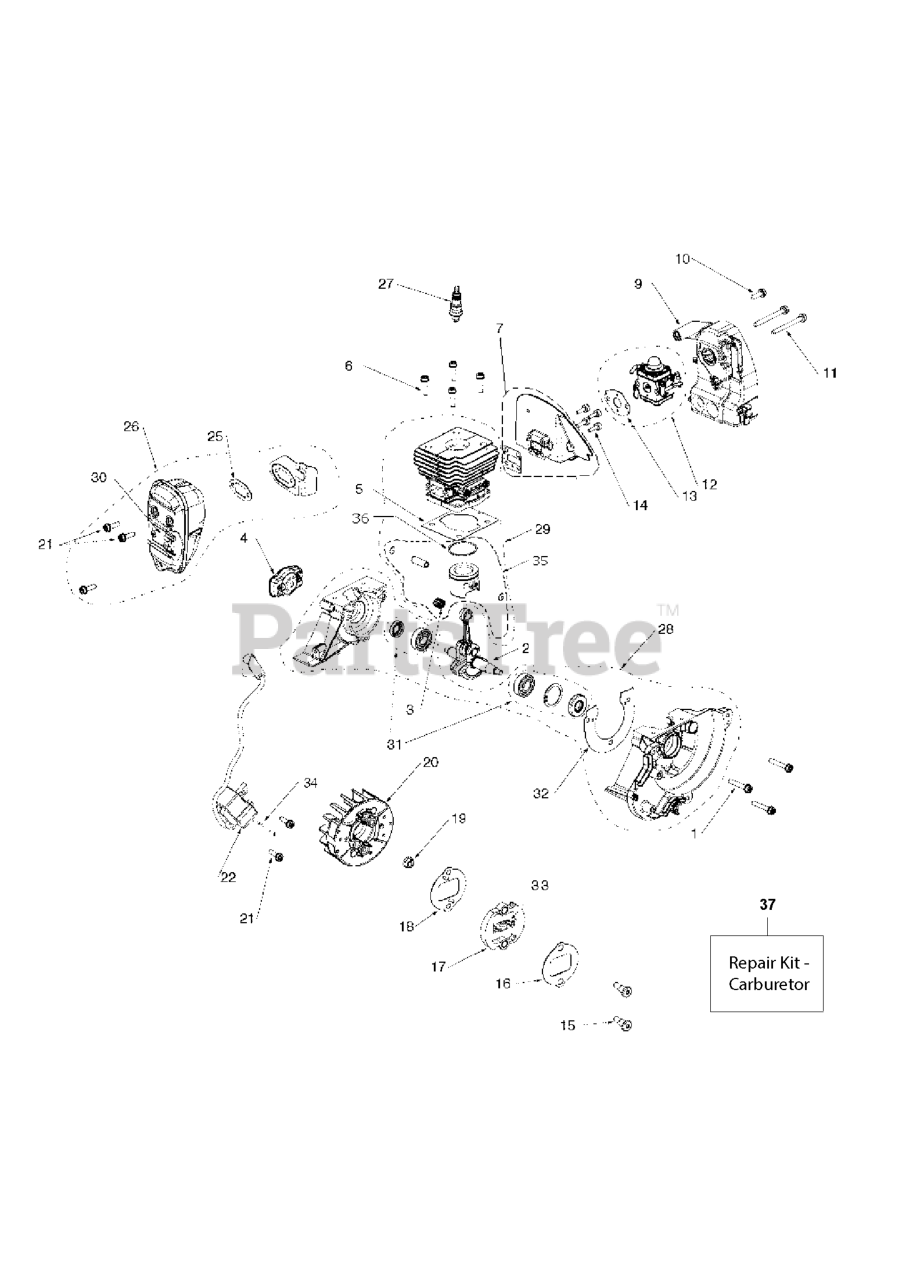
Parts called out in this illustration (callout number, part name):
2	CRANKSHAFT ASSY
4	STARTER PAWL BRIDGE
5	GASKET CYLINDER BASE
7	KIT
9	ASSY FILTER HOLDER
12	KIT CARBURETOR
13	GASKET CARB ADAPTER
14	SCREW ITXSCM
15	SCREW CLUTCH
16	WASHER CLUTCH UPPER
17	ASSY CLUTCH
18	WASHER CLUTCH LOWER
19	FLANGE NUT
22	Ignition Module
26	MUFFLER KIT
27	KIT SPARK PLUG
28	KIT CRANKCASE ASSY
29	KIT PISTON/CYLINDER
30	KIT SPARK ARRESTOR
31	SEAL KIT AND BEARING
32	GASKET CRANKCASE
33	SPRING CLUTCH
34	CABLE SHORT CIRCUIT ENGINE
35	KIT PISTON 129
36	PISTON RING 36MM
